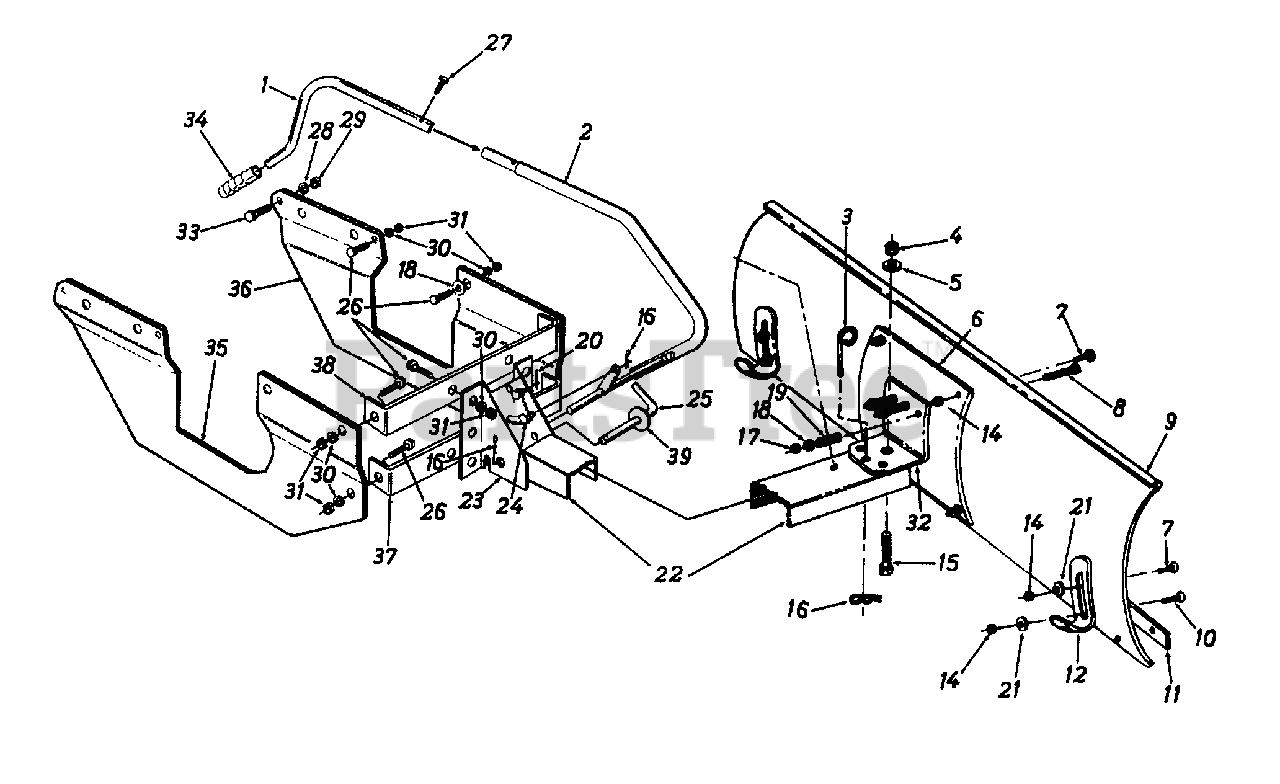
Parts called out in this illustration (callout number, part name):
1	Upper Lift Handle
2	Lift Handle Ass'y.
3	Pivot Lock Pin
4	Hex Cent. L-Nut 1/2-13 Thd.
5	Fl-Wash. 17/32" I.D.
6	Reinforcement Plate
7	Carriage Bolt 5/16-18 x .75" Lg.
8	Hex Bolt 3/8-16 x 4" Lg.
9	42" Blade
10	Carriage Bolt 5/16-18 x 1" Lg.
11	42" Wear Plate
12	Shoe Skid
14	Hex Cent. L-Nut 5/16-18 Thd.
15	Hex Bolt 1/2-13 x 1.25" Lg.
16	Int. Cotter Pin
17	Hex Cent. L-Nut 3/8-16 Thd.
18	Fl-Wash. 3/8" I.D.
19	Compression Spring
20	Cotter Pin 1/8" Dia. x 1" Lg.
21	Fl-Wash. 5/16" I.D.
22	Push Bar Channel
24	Lift Link
25	Channel Pivot Shaft
26	Hex Bolt 3/8-16 x 1" Lg. Grade 5
27	Hex Bolt #10 x 5/8" Lg.
28	L-Wash. 1/4" I.D.
29	Hex Nut 1/4-20 Thd.
30	L-Wash. 3/8" I.D.
31	Hex Nut 3/8-16 Thd.
32	Support Bracket
33	Hex Bolt 1/4-20 x .75" Lg.
34	Rubber Grip
35	Frame Support Brkt. (R.H.)
36	Frame Support Brkt. (L.H.)
37	Support Brkt.
38	Support Brkt.
39	Fl-Wash. 17/32" I.D. x 1" O.D.
